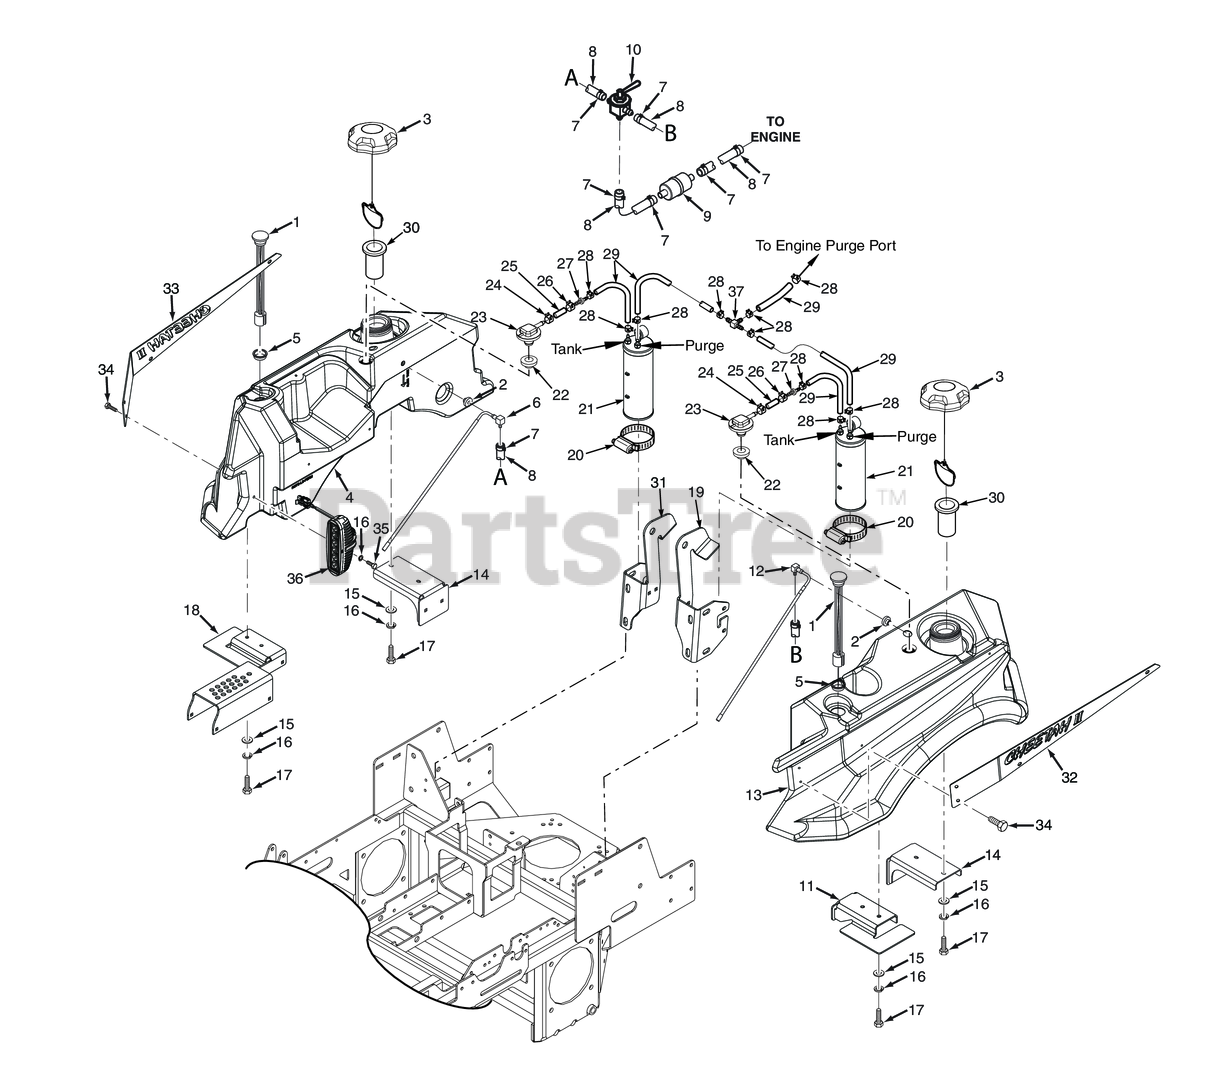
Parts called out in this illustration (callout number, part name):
1	Fuel Gauge Assembly
2	Bushing, 0.56" Dia. Viton
3	Fuel Cap w/ Tether (E.P.A.)
3	Fuel Cap w/Tethered - California Models Only
4	Fuel Tank Assembly, RH
5	Grommet, Fuel Gauge
6	Fuel Tube Assembly
7	Clamp, Fuel Hose 1/4" Hose I.D.
8	Fuel Hose, 1/4" I.D. Non-Perm (791DFI Fuel Return) - Order by Inch
9	Fuel Filter
10	Valve, Fuel Shut-Off
11	Mounting Bracket, Fuel Tank Front
12	Fuel Tube Assembly, LH
13	Fuel Tank Assembly, LH
14	Mounting Bracket, Fuel Tank Rear
15	Flatwasher, 5/16-.375 x .875 x .083 (35BV & 37BV-EFI)
16	Lockwasher, 5/16 (.317 x .586 x .078) Helical Spring
17	BOLT, SERRATED FLANGE HEX HEAD 5/16-18 X 3/4"
18	Adjustment Bracket, Upper Cut Height
19	ROPS Mount, LH, 29CV-EFI
20	Clamp, 3-1/2" Max. Dia.
21	Carbon Canister - SVR-52V / SVR-61V
22	Grommet, Viton,
23	Remote Vent, No Valve
24	CLAMP, FUEL HOSE(KAWASAKI ONLY)
25	Hose, 1/4" Vapor Recovery (order by inch)
26	CLAMP, FUEL HOSE(KAWASAKI ONLY)
27	Mender, 1/4 x 3/16 w/0.02 Hole
28	Clamp, Vapor Recovery Hose 3/16"
29	Hose, Vapor Recovery 3/16" (order by inch)
30	Tube, Fuel Tank Insert - 4"
31	ROPS Mount, RH, 29CV-EFI
32	Plate, LH Fuel Tank
33	Plate, RH Fuel Tank
34	CAP SCREW, 1/4-20 X 1/2" SERRATED FLANGE HEX
35	SOC HD CAPSCR, 5/16-18 X .75
36	Light Assembly
37	Tee, 3/16 x 3/16 x 3/16 Union, Hose Barb
